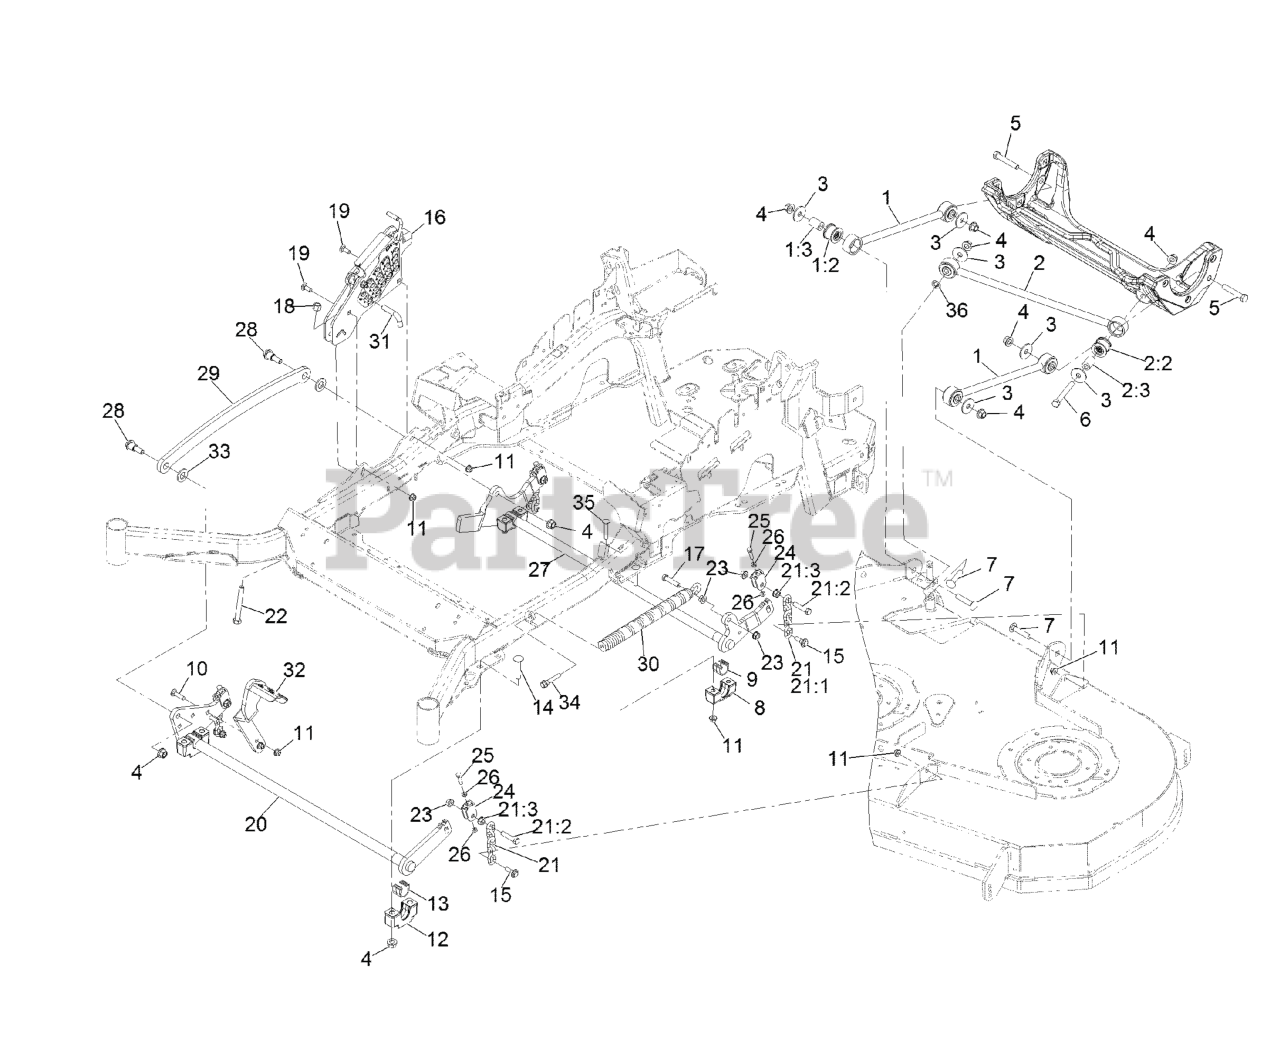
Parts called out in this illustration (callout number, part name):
1	DECK STRUT ASM
1:2	BUSHING-SUSPENSION, RUBBER
2	PANHARD ROD ASM
2:2	BUSHING-SUSPENSION, RUBBER
3	WASHER-THRUST
4	Nut-Lock 1/2-13
5	SCREW-HH
6	SCREW-HH
7	SCREW-CARR
8	SUPPORT-CROSS SHAFT, BEARING REAR
9	BEARING-CROSS SHAFT, REAR
10	SCREW-CARR
11	NUT-HF, NI
12	SUPPORT-CROSS SHAFT, BEARING
13	BEARING-CROSS SHAFT, FRON
14	Bolt-Carriage 1/2-13 X 2 1/2 Spl Neck
15	SCREW-SHOULDER, HHF
16	HOC ASM
17	SCREW-HH
18	NUT-LOCK, NI
19	BOLT-CARR
20	DECKLIFT-FRONT
21	DECK LIFT CHAIN ASM
21:1	CHAIN-LIFT, DECK
21:2	SCREW-HH
22	BOLT-TAP
24	YOKE-ADJUST, DECK
25	SCREW-HH
26	NUT-JAM
27	LIFT-DECK, REAR
28	SCREW-SHOULDER, HHF 1/2-13 X 1.12
29	LINK-LIFT, DECK
30	SPRING-EXTENSION
31	PIN-HOC
32	LEVER-FOOT
33	WASHER-FLAT
34	BOLT-SHOULDER
35	Bolt-Carriage 3/8-16 X 2 1/4
36	NUT-PUSH
